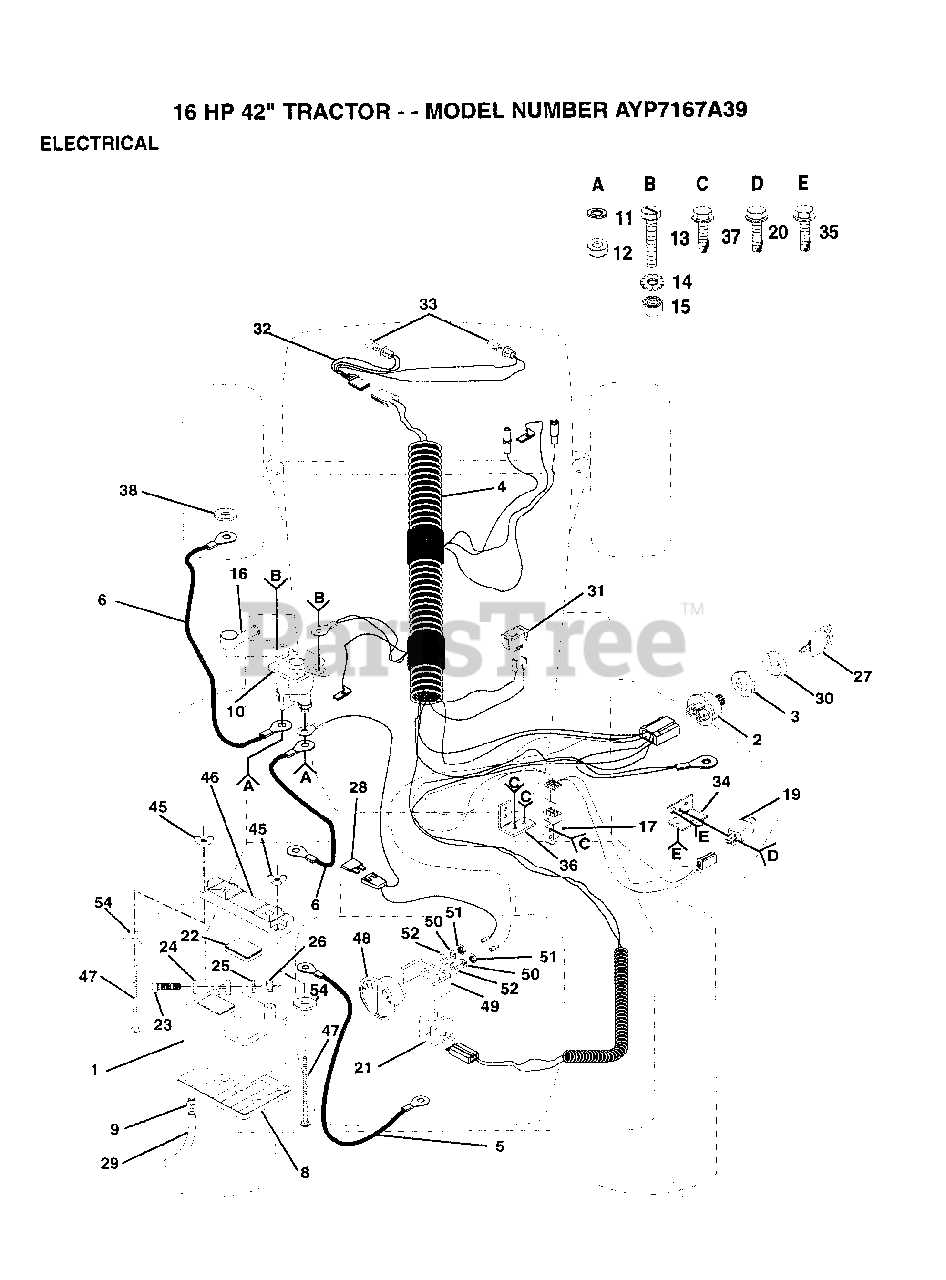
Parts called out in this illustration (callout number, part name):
3	NUT IGNITION
5	CABLE T
6	CABLE-BATTERY T
8	"TRAY T, BATTERY"
9	HOSE CLAMP T
12	NUT
13	BOLT
15	NUT
17	SWITCH INTERLOCKT
19	SWITCH-INTER. GT
20	SCREW
21	SWITCH SEAT
22	"CAP,BATTERY "
23	BOLT LT
24	WASHER
25	LOCKWASHER
27	KEY
28	FUSE HYT
31	SWITCH LT
33	HEADLAMP BULB
34	BRACKET LT
35	SCREW
36	SWITCH BRACKET
37	SCREW
47	BOLT
48	AMMETER T
52	WASHER
53	WIRE TIE
54	WASHER
